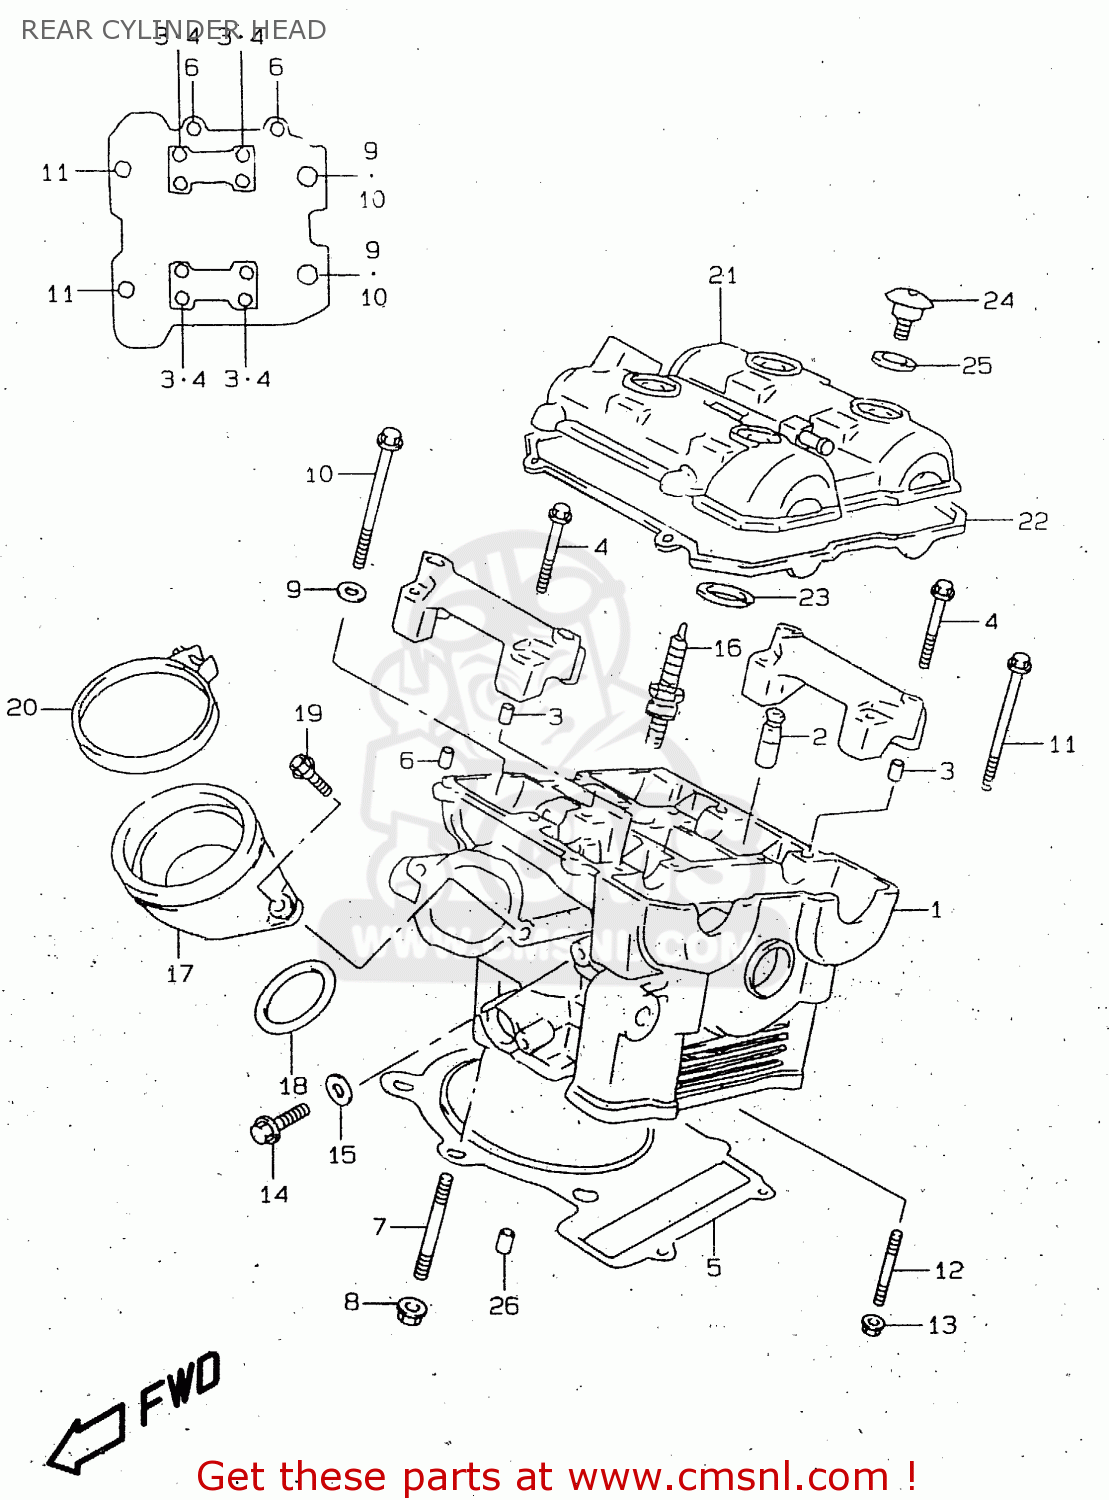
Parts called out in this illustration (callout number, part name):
1	HEAD ASSY,CYLINDER
2	GUIDE,VALVE
3	PIN(6.2X8X11)
4	BOLT(6X39)
5	GASKET,CYLINDER HEAD (NAS)
6	PIN
7	BOLT,STUD
8	NUT
9	WASHER(10.5X19X2)
10	BOLT,CYLINDER HEAD(L:175)
11	BOLT(6X70)
12	BOLT,STUD
13	NUT
14	BOLT
15	GASKET(5.8X13X1.2) (NAS)
16	PLUG,SPARK(CR9EK)
17	PIPE ASSY,INTAKE
18	O RING(D:2.4,ID:55.6)
19	SCREW
20	CLAMP
21	COVER COMP,CYLINDER HEAD
22	GASKET,CYL HEAD COVER NO.1 (NAS)
23	GASKET,CYL HEAD COVER NO.2
24	BOLT(7X17.5)
25	WASHER(10.6X25.5X2.3)
26	PIN(6.2X8X11)
